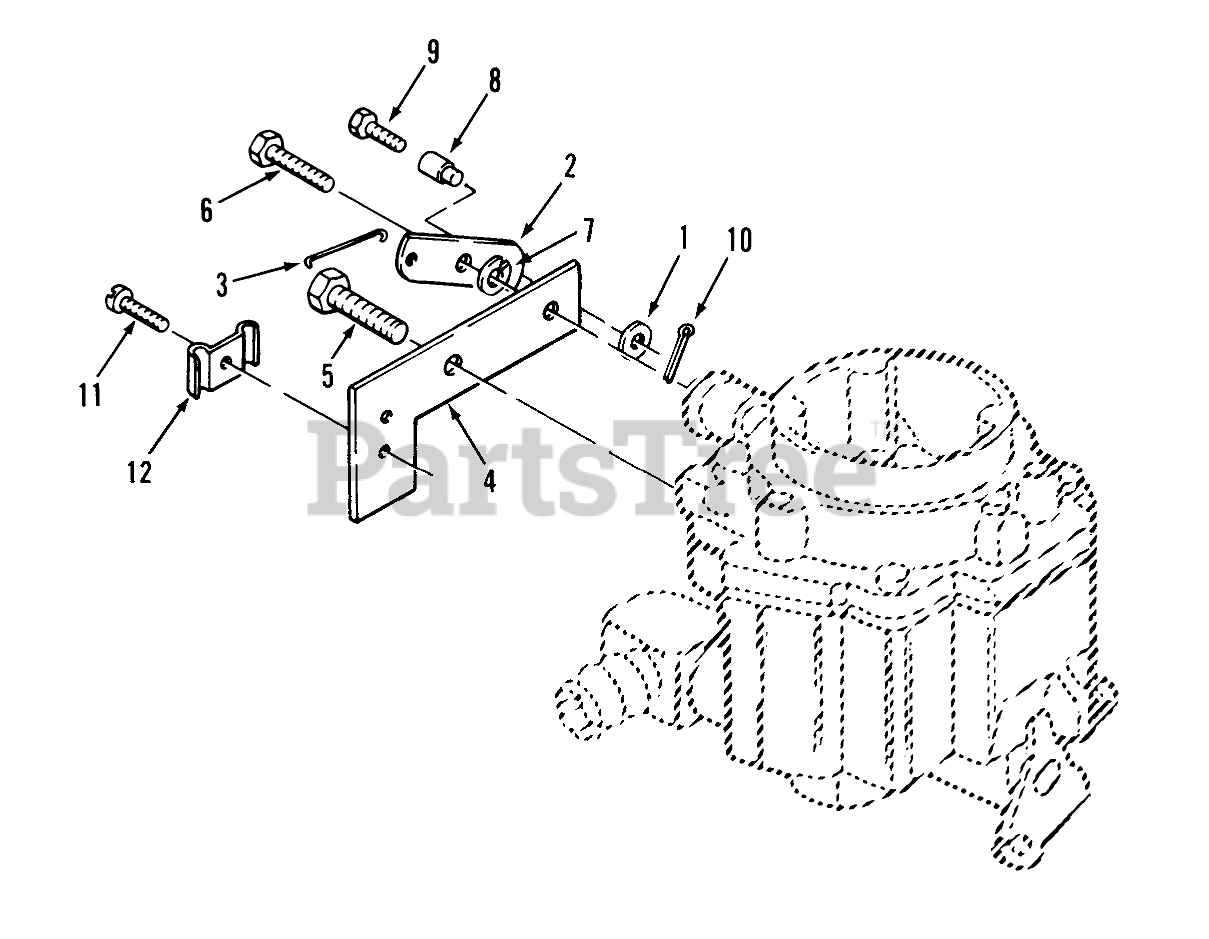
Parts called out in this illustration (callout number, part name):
1	Washer
2	SWIVEL-CHOKE
3	LINK-CHOKE
4	BRACKET
5	SCREW-HWH
6	BOLT-SHOULDER
7	WASHER-LOCK
8	SWIVEL
9	SCREW
10	PIN-COTTER
11	SCREW-TAPPING
